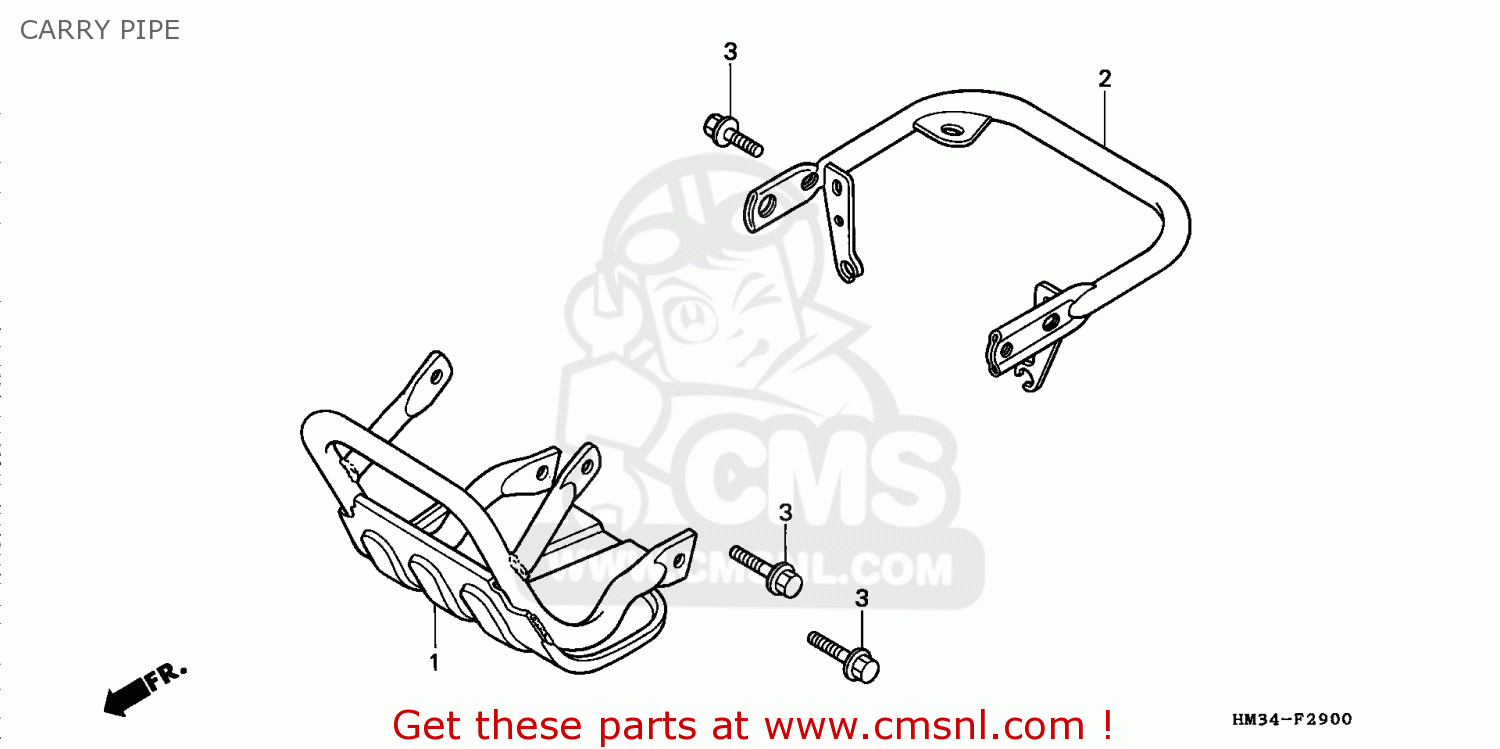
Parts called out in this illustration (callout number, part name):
1	PIPE COMP*NH262M*
2	PIPE COMP*NH262M*
3	BOLT FLANGE 8X20
